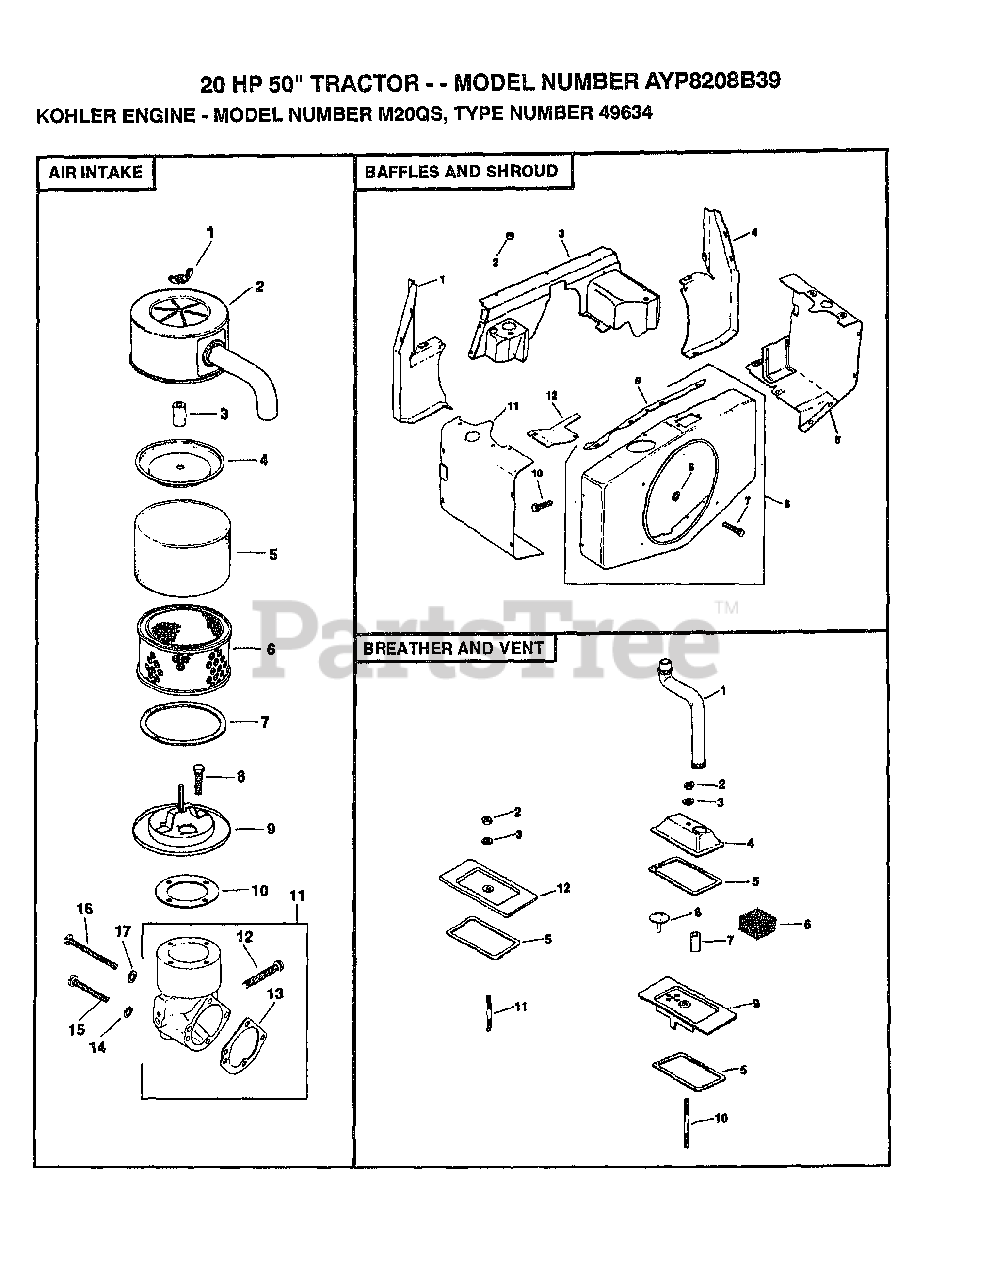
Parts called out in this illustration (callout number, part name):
1	DUCT, AIR, #1 SIDE
1	HOSE, BREATHER
2	COVER, AIR CLEANER
3	SEAL ELEMENT
3	COVER, AIR DUCT
4	COVER AIR CLEANER ELEMENT
4	DUCT, AIR #2 SIDE
5	BAFFLE, #1 CYLINDER HEAD
6	KIT, BLOWER HOUSING
6	FILTER, BREATHER
7	SEAL BREATHER
8	VALVE, BREATHER
9	COVER, #1 LOWER CYLINDER VALVE
11	BAFFLE, #2 CYLINDER HEAD
12	BAFFLE, #2 CYLINDER TOP
12	COVER, #2 CYLINDER VALVE
13	GASKET, AIR CLEANER
